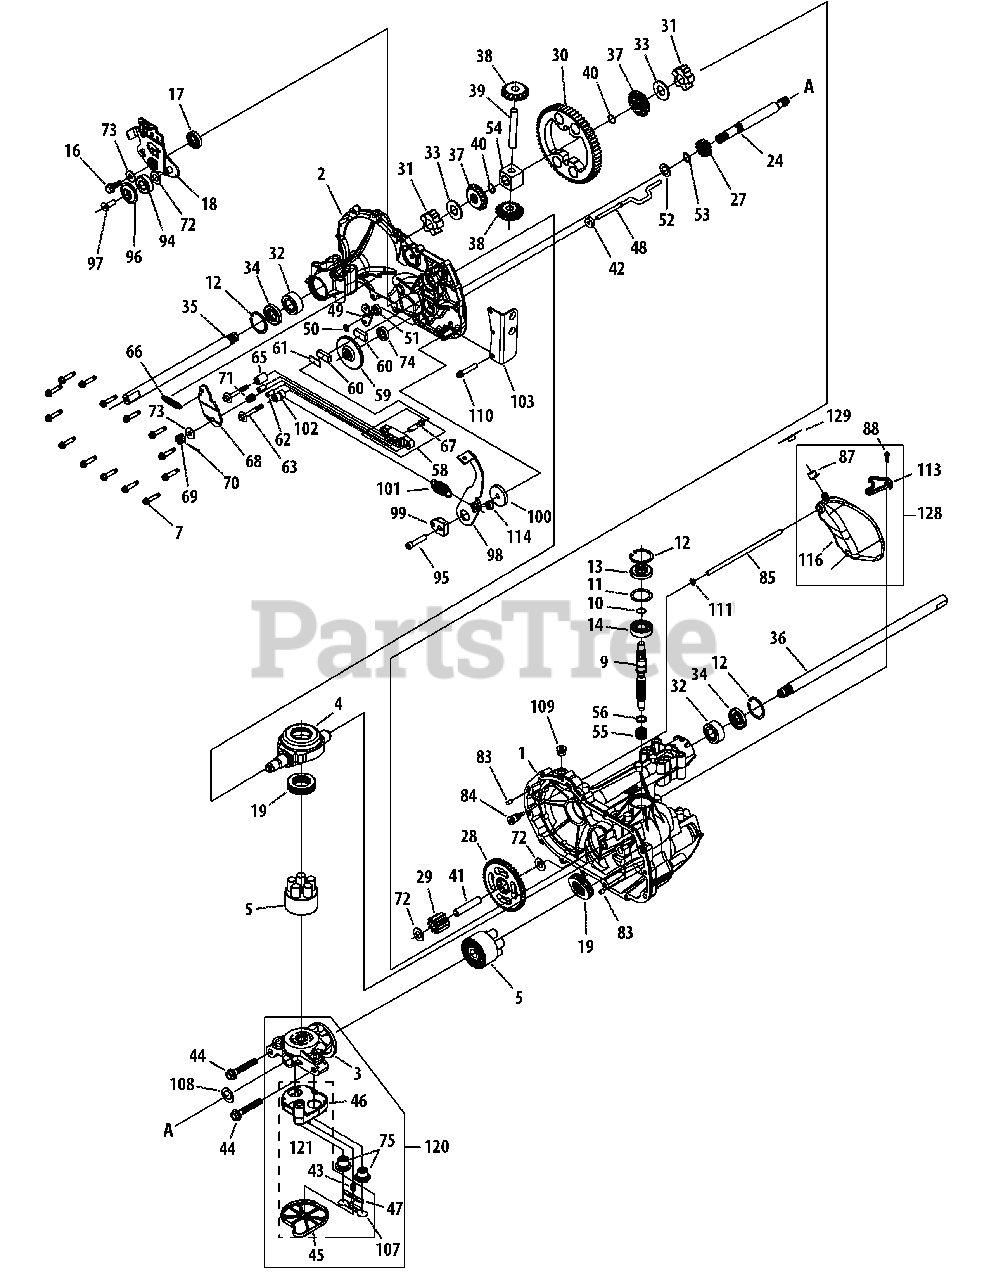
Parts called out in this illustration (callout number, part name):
1	Main Housing Assembly
1	Main Housing, Machined
1	Bushing ,865 x 985 x .790
2	Main Housing Assembly
2	Main Housing, Machined
2	Bushing ,865 x 985 x .790
2	Bushing 624 x 719 x . 562
3	Center Section Assembly
3	Center Section Machined
3	Bushing. 707 x . 788 x . 591
4	Swashplate, Trunnion Machined
5	Block - Assembly
5	Block - Cylinder
5	Piston
5	Spring, Compression
5	Washer - Thrust
7	Hex Flange Screw 1/4-20 x-1,25
9	Shaft, Input
10	Ring - Retaining
12	Ring - Retaining
13	SeaL Lip .67 x 1.58 x .276
14	Ball Bearing 17mm Id x 40mm Od
16	Bolt. Flange 5/16-24 x .94 (Patch)
17	Lip Seal 18 x 32 x 7
18	Arm Control
19	Bearing 30x52 x 13 Thrust
24	Shaft Motor
27	Gear - Pinnion 12t
28	10t/49t Gear
29	Gear Jot Jackshaft
30	60t Bull Gear
31	Sleeve Bearing . 75 x 1.750 x .625
32	Sleeve Bearing .75 x 1.575 x ,625
33	Washer 3/4 Id x 1-1/2 Od x .13 Thk
34	Lip Seal Axle Seal
35	Shaft Axle . 75 x 11. 39 ( Dd R. H, )
36	Shaft Axle .75 x 17. 99 ( Dd, L, H.)
37	Miter Gear (Splined)
38	Miter Gear 15t (0 .5 Id)
40	Ring, Spiral Retaining
41	Pin, Jackshaft
42	Magnet, Ring
43	Spring, Bypass
44	Hydro Mtg Screw 3/8-24 x 2.5
45	Bottom, Filter
46	Base Filter W/ Poppet
47	Actuator Bypass
48	Rod Bypass Actuator
49	Arm, Bypass
50	Retaining Ring 0.250 External
51	Seal, Lip . 741 x .250 x .250 Tc
52	Flat Washer 5/8 Id x 1.0 Od x . 05
53	Retaining Ring
54	Bearing, Center Block
55	Spring - Helical Compression
58	Kit, Brake Yoke
58	Brake Yoke
58	Sq. Hd, Bolt 5/16-24 Ribbed
59	Rotor, Brake
60	Brake Puck
61	Puck Plate
62	Brake Actuating Pin
63	Hex Screw 1/4-20 x 2 w/ Patch
66	Kit, Spring
67	So. Hd, Bolt 5/16-24- Ribbed
68	Arm, Brake
69	Slotted Hex Nut 5/16-24
70	Cotter Pin 3/32 x 3/4
71	Comp. Spring Brake Anti-Drag
72	Washer, Ht .5 I. D. x 1 OD, x .032
73	Flat Washer, 11/32 ID x 7/8 OD
74	Kit, Seal
74	Oil, Seal 625 x Lo x .25
74	Ring, Ret-Star Washer
74	Bulletin, Shaft Seal
75	Check Plug Assem, .027 Washer
83	Pin, Standard Headless
84	Fitting, 5/16 Sae 5/32 Tube
85	Hose, Expansion Tank
87	Cap,. Vent
88	Bolt, Self Tapping 10-32 x 112
94	Ball Bearing .62 Id x 1,38 x 44
95	Cap Screw, 5/16-24 x 1-112
96	Spacer, Locating
97	Screw, Sfhcs
98	Arm, Return
99	Puck, Adjusting
100	Washer, .32 OD x 1.6 ID x .24
101	Spring, Extension
102	Spacer, .56 x .26 x .87
103	Bracket, Torque
107	Deflector
108	Washer, Motor Shaft .71 Id 1.15 Od
110	Torx Head Screw, 5/16-18
111	O-Ring, .07 x .301 ID
113	Bracket, Support Expansion Tank
114	Spring Guide
116	Silicon Sponge
120	Center Section - Bypass Assm
120	Center Section Machined
120	Base Filter w/ Poppet
120	Check Plug Assembly
120	Spring Bypass
120	Actuator Bypass
120	Deflector
120	Bottom, Filter
120	Bushing, .707 x .788 x .591
121	Filter Assembly
121	Bottom Filter
121	Base Filter w/ Poppet
121	Spring Bypass
121	Actuator Bypass
121	Deflector
128	Kit, Expansion Tank
128	Tank, Expansion
128	Cap, Vent
128	Bolt, Self Tapping 10-32 x 1/2
128	Bracket, Support Expansion Tank
128	Silicon-Sponge 112 x 1/2 x 3/16
129	Cap, Expansion Tank Shipping
